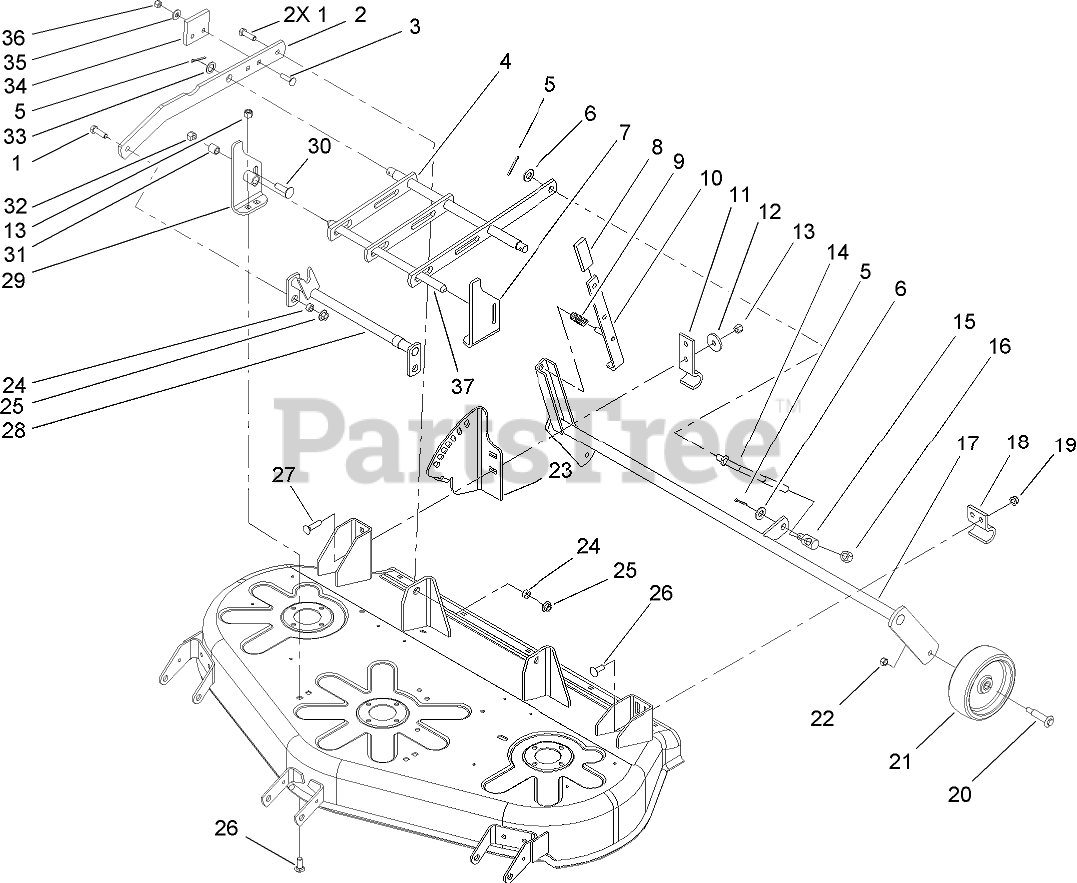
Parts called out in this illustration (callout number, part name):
1	SCREW-HH
2	BAR-DRAFT
3	SCREW-CARR
4	BAR-LEVELER
5	PIN-COTTER
6	WASHER-FLAT
7	BRACKET-FRONT DECK, LH
9	SPRING-COMPRESSION
10	LEVER-HOC
11	BRACKET-PIVOT
12	WASHER-SUPPORT
13	NUT-LOCK, NI
14	ROD-ADJUSTING
15	TRUNNION
16	NUT-LOCK, NI
17	WHEEL SUPPORT ASM
19	NUT-FLANGE
20	BOLT-SHOULDER
21	WHEEL
22	NUT-HEX
23	QUADRANT
24	SPACER
25	LOCKNUT-FLANGE
26	BOLT-CARR
27	SCREW-CARR
28	HITCH ASM
29	BRACKET-FRONT DECK, RH
30	BOLT-CARR
31	SPACER
32	NUT-LOCK, NI
33	WASHER-FLAT
34	BUMPER
35	WASHER-FLAT
36	NUT-LOCK, NI
37	Shaft-Front
